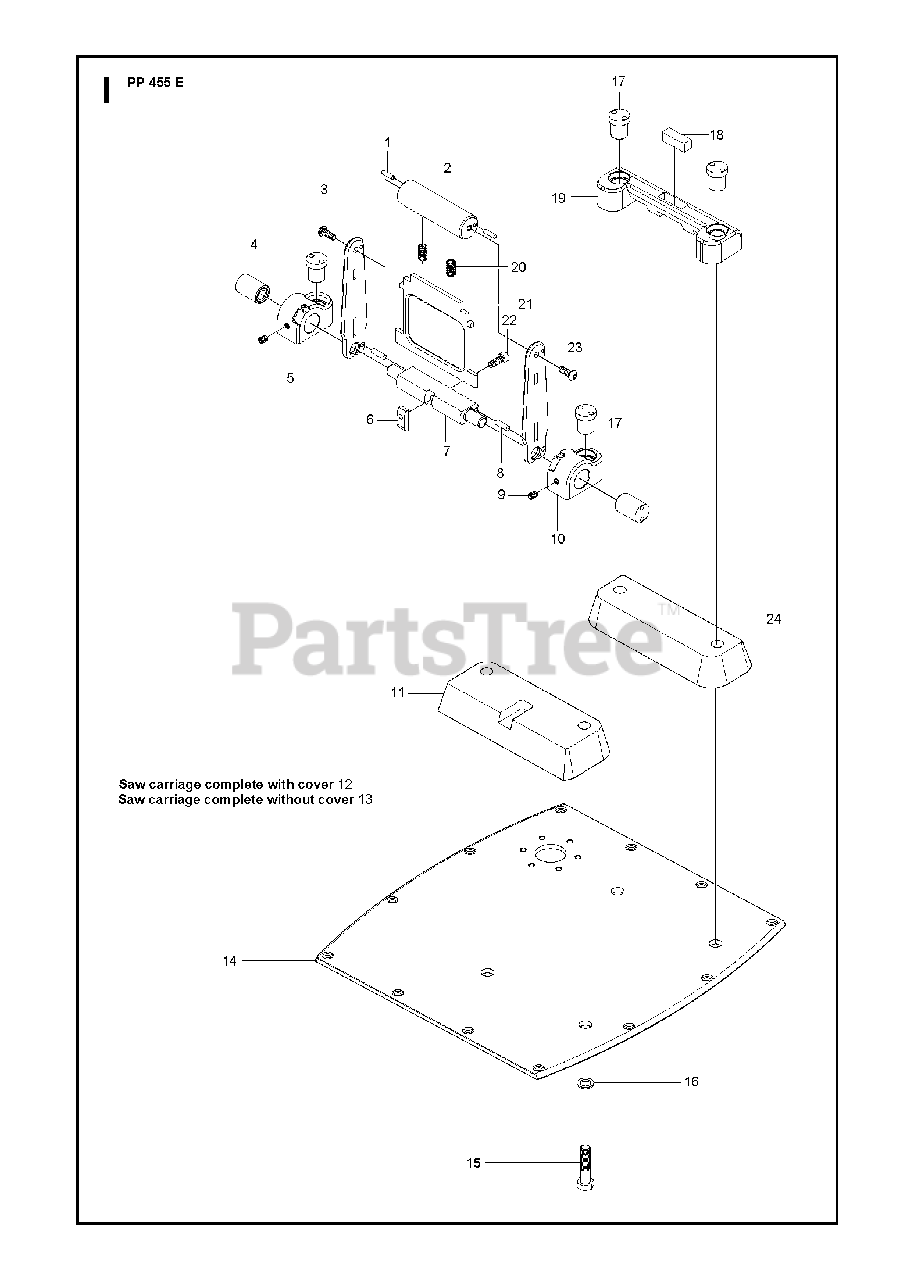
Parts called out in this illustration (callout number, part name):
12	COVERSaw carriage complete with cover
13	BRACKETSaw carriage complete without cover
16	SEALING WASHER
